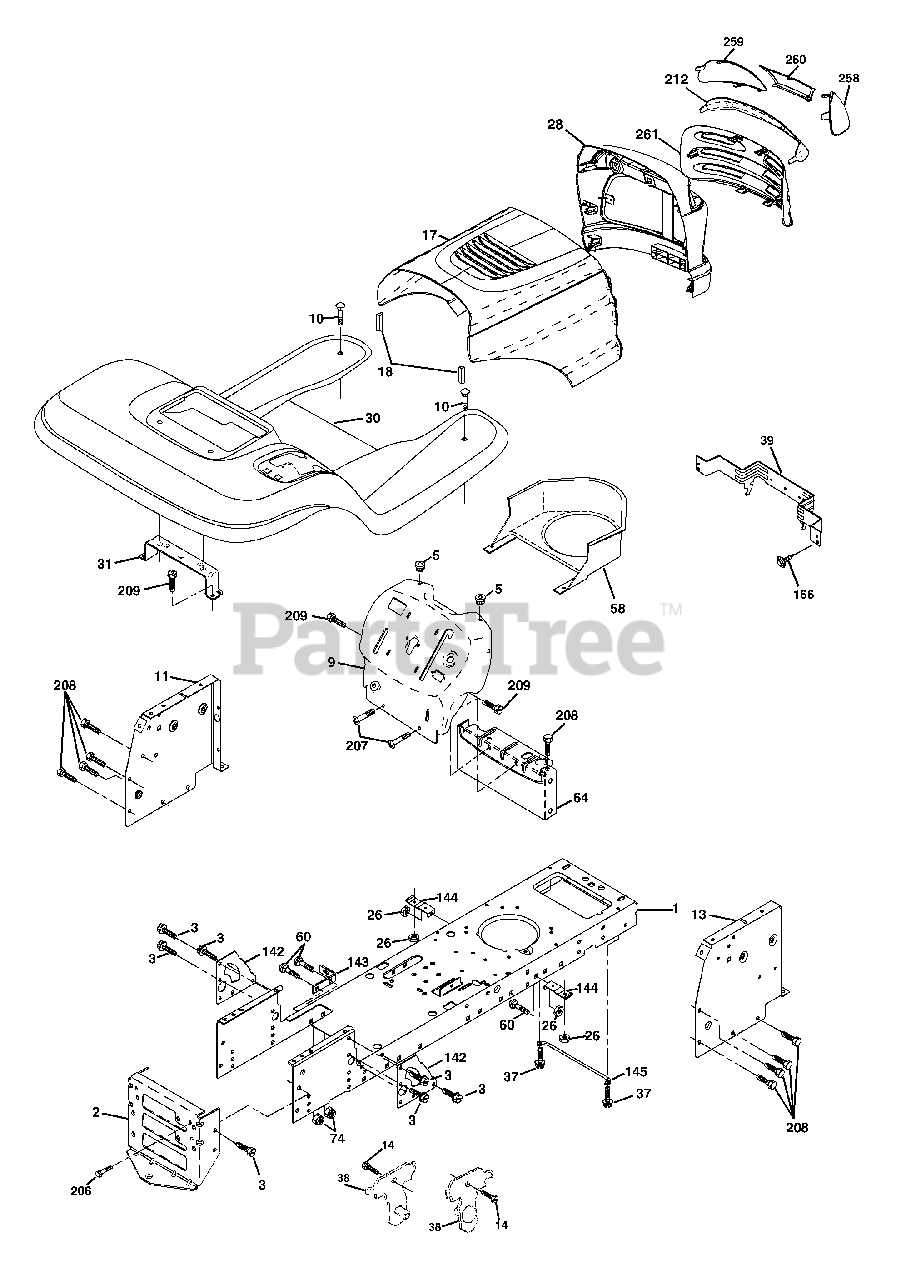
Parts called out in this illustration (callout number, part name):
1	Chassis Stamping
3	Screw 3/8-16x3/4
9	Dashboard
10	Bolt Rdhd Sqnk 3/8-16 Unc x 1
11	Panel Dash Lh
13	Panel Dash Rh
14	Screw Thdrol 3/8-16 x 1/2
17	Hood
18	Bumper Hood
26	Nut Lock w/Insert 3/8-16 UNC
28	Grille Lens Asm
30	Fender
37	Screw Thdrol 5/16-18 x 1/2
38	Bracket Asm Pivot Mower Rear
39	Bracket Pivot Hood
60	Bolt RDHD SQNK 3/8-16 x 3/4
64	Dash Lower Stlt
74	Nut Crownlock 3/8-16
142	Plate Reinforcement Stlt
143	Bracket Swaybar Chassis
144	Bracket Ft Rest
145	Rod Pivot Chassis Hood
166	Screw Hw Hd Hi-Lo #13-16 x 3/4
206	Bolt Shoulder 5/16-18 TT
207	Screw Thdrol 5/16-18 x 1/2 TYTT
208	Screw Thdrol 3/8-16 x 1/2 Ty-TT
209	Screw 3/8-16 x 3/4
212	Insert Lens Reflect
258	Lens RH
259	Lens LH
260	Cover Lens
261	Insert, Grille
